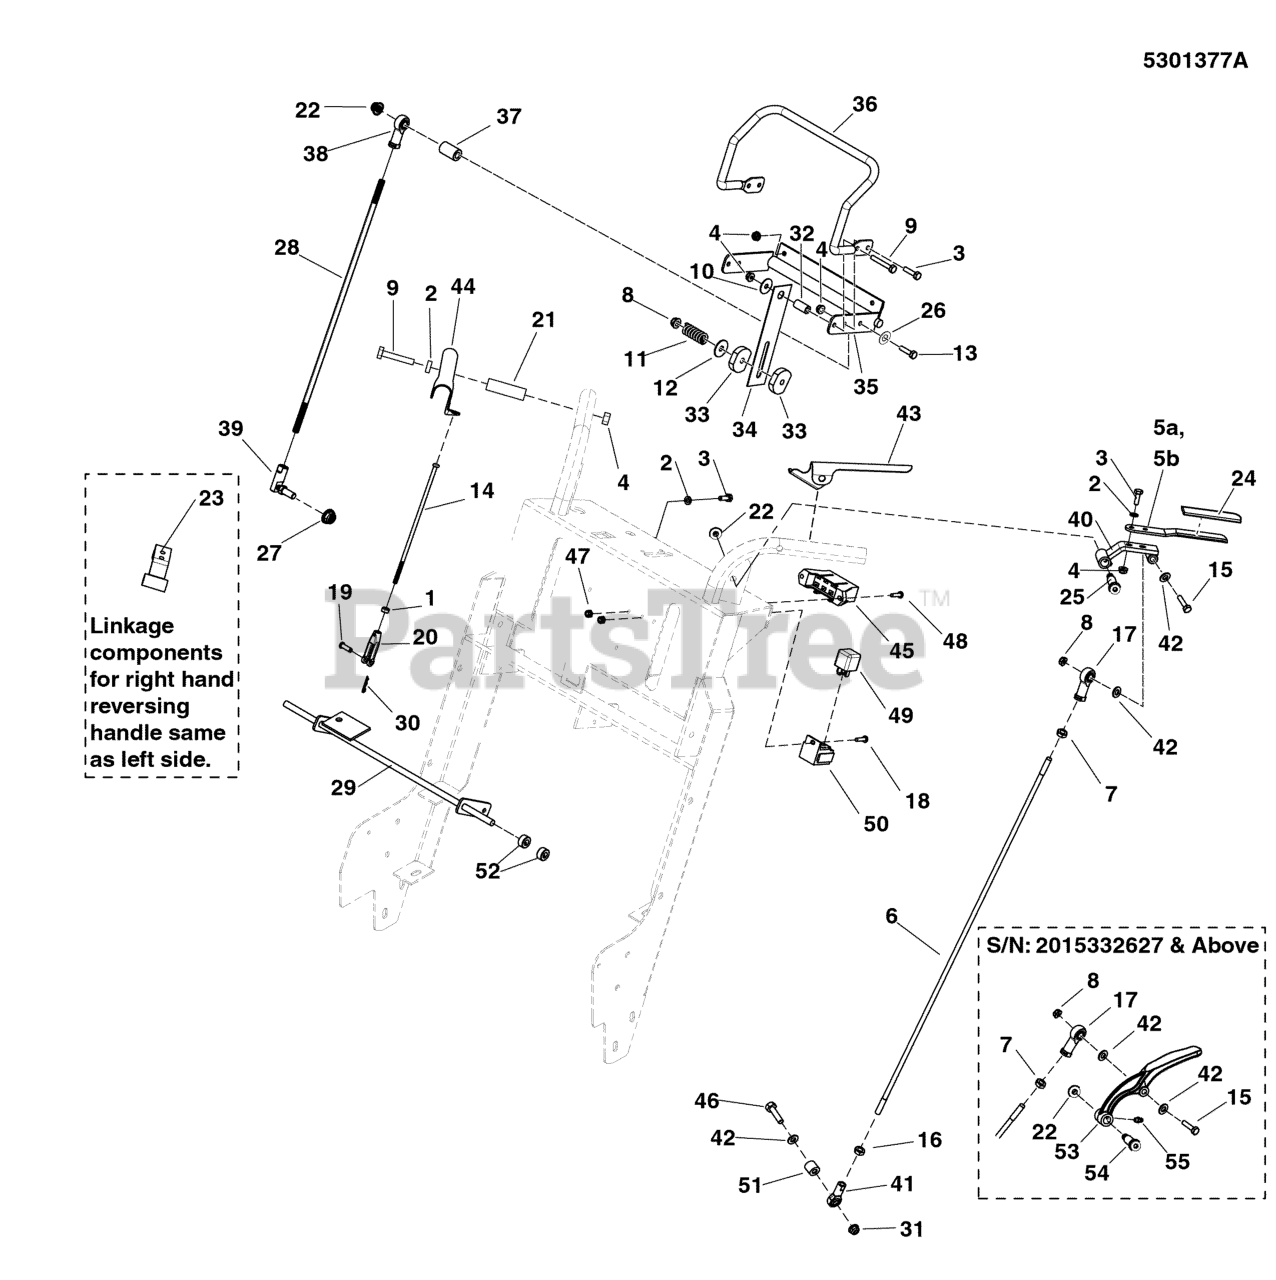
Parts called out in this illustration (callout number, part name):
1	HN, 1/4F GR5 YZ
2	WASHER, 1/4 SAE
3	BOLT, 1/4-20 X 3/4 GD5 YZ
4	NUT, 1/4-20 HEX NYLOCK FLANGE
6	ROD, 5/16-24 X 33.2 LH-RH, CZ
7	NUT, 5/16-24 HEX, LH
8	NUT, 5/16-18 HEX NYLOCK FLANGE
9	BOLT, 1/4-20 X 1-3/4" GD5 YZ
10	WASHER, 1/4" FENDER
11	SPRING-COMP, .428IDX2.50LGX.154WR, BZ
12	WASHER, 5/16" FENDER
13	BOLT, 3/8-16 X 2-1/2" GD5 CZ
14	ROD, OPC LINK
15	BOLT, 5/16-18 X 2, GD5
16	NUT, 5/16-18 HEX JAM
17	BALL JOINT 5/16-24 LH FEMALE BRONZE RACE
18	SCREW, #10-24 X 1/2 ROUND PHILLIPS
19	PIN, CLEVIS, 1/4 X 7/8, PLATED
21	SPACER, .26 X .38 X 1.250 YZ
22	NUT, 3/8-16 HEX NYLOCK FLANGE
23	WELD, REVERSE HANDLE - RH
24	GRIP, FOAM, 1/4 X 1 X 4.1
25	BOLT, 3/8-16 x 1-1/2", 1/2" SHOULDER
26	WASHER, 3/8 SAE
27	NUT, 3/8-24 HEX NYLON LOCK
28	ROD, CRUISE CONTROL, SNP PRO WB
29	WELD, OPC SHAFT, RED
30	PIN, HAIR, .0585 X 1-1/8, 1/4 EYE YZ
31	NUT, 5/16-18 HEX NYLOCK FLANGE
32	SPACER, .26 X .50 X 1.00 YZ
33	SPACER, .34 X 1.54 X .25 UHMW
34	PLATE, FRICTION CONTROL
35	WELD, SPEED CONTROL,DDS - RED
36	BAR, SPEED CONTROL, DIPPED
37	SPACER, .38 X .75 X 1.25, YZ
38	ROD END, 3/8-24 LH FEMALE
39	BALL JOINT, 3/8-24 FEM, STUD.
40	WELD, REVERSE HANDLE - LH
41	BALL JOINT 5/16-24 RH FEMALE BRONZE RACE
42	WASHER, 5/16" SAE
45	FUSE BLOCK
46	BOLT, 5/16-18 X 1-1/2 GD5 YZ
47	NUT, 5/16-24 HEX
48	SCREW, #10-24 X 3/4 ROUND PHILLIPS
49	RELAY, 12V, 40A
50	SOCKET, RELAY (SEE ELECTRICAL SCHEMATICS)
51	SPACER, .33 X .50 X .25, CZ
52	COLLAR, 3/8 SET
53	HANDLE, REVERSING - BLK
54	BOLT, 3/8-16 X 1, 1/2 SHOULDER
55	GREASE FITTING, 1/4-28 STRAIGHT
